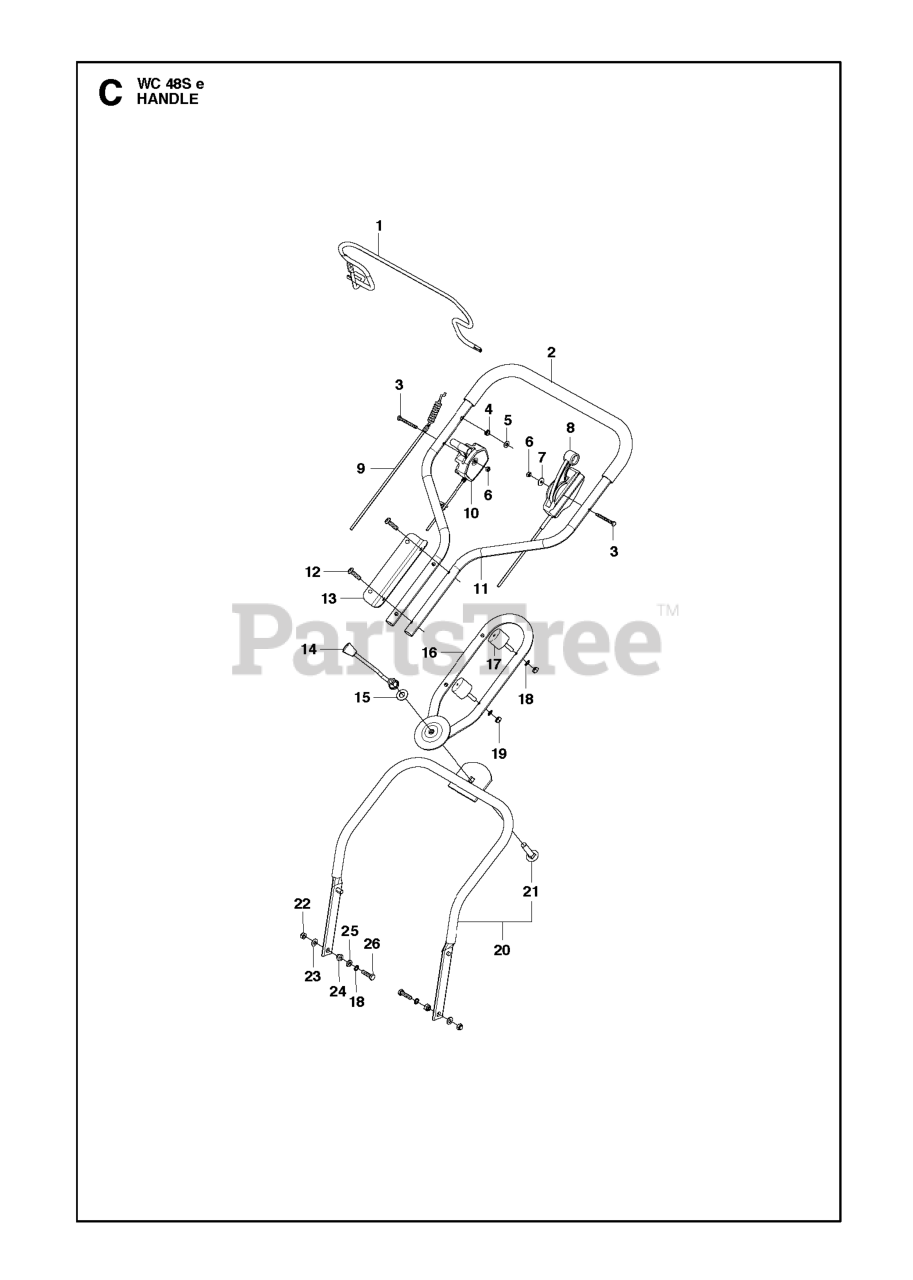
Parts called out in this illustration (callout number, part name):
3	SCREW M6X55
6	NUT FLANGE - M6
19	NUT
22	NUT LOCK - M8, NYLOCK
